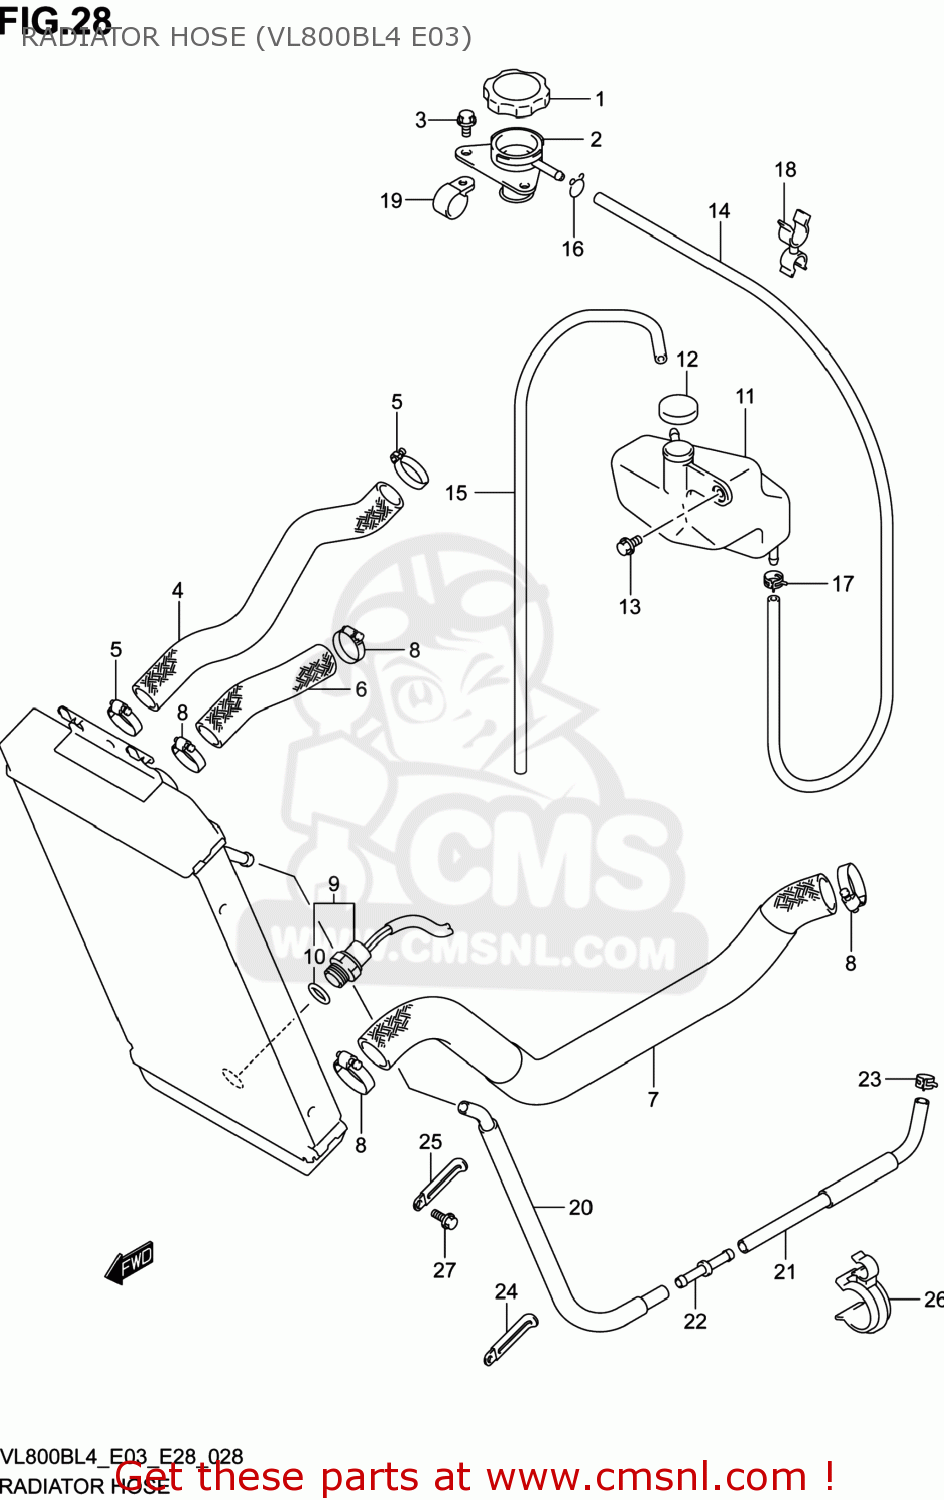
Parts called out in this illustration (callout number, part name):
1	CAP,RADIATOR
2	CONDUCTION,RADIATOR
3	BOLT
4	HOSE,CONDUCTION
5	CLAMP
6	HOSE,RADIATOR INLET
7	HOSE,RADIATOR OUTLET
8	CLAMP
9	SWITCH,RADIATOR FAN
10	O-RING
11	TANK,RESERVOIR
12	CAP,RESERVOIR TANK
13	BOLT(6X12)
14	HOSE,RESERVOIR INLET
15	HOSE,RESERVOIR TANK INLET
16	CLIP
17	CLIP
18	CLAMP
19	CLAMP
20	HOSE,WATER BYPASS
21	HOSE,WATER BYPASS
22	JOINT
23	CLIP
24	CLAMP(L:80)
25	CLAMP(L:82)
26	CLAMP
27	BOLT(10X16)
